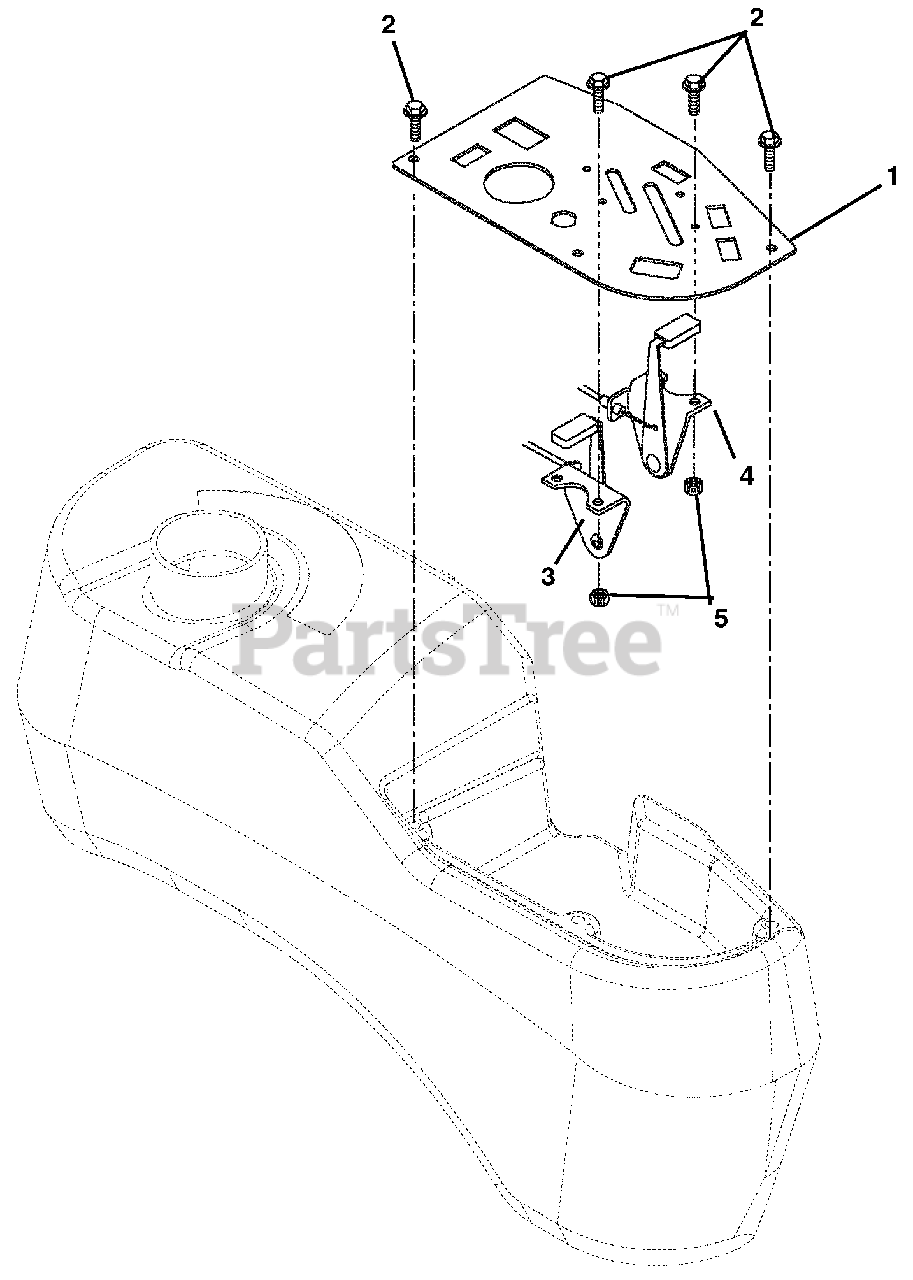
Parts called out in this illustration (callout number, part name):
1	Panel, Control
2	Screw, Machine 10-24 x .50 Hex Washer Head (045, 046, 047, 049, 052, 053)
3	Throttle, Control
4	Choke Control (045, 046, 049)
5	Nut, Locking Nylon 10-24 With Insert (045, 046, 047, 049, 052, 053)
